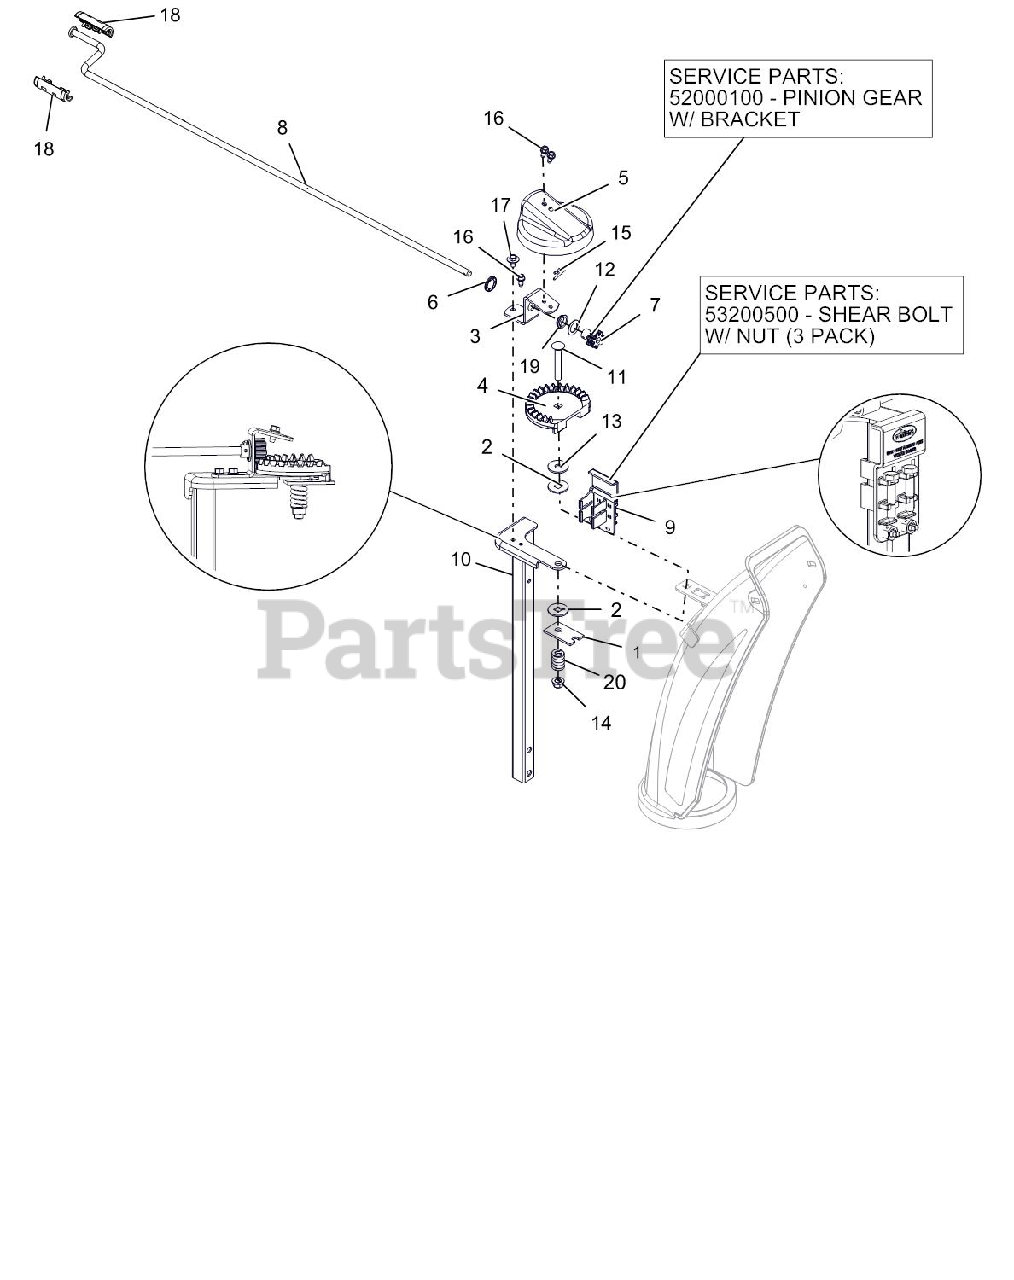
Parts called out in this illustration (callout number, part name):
1	PLATE, FRICTION
2	FRICTION WASHER
3	BRACKET, PINION GEAR
4	CHUTE GEAR
5	GEAR COVER
6	PUSHNUT .625
7	PINION GEAR W/BRACKET
7	PINION GEAR - CHUTE
8	ROD, CHUTE CRANK, COMP&SNOTEK
9	SHEAR BOLT WITH NUT
9	HOLDER W SMALL SHEAR BOLT /NUT
10	CHUTE PEDESTAL, TALL COMPACT
11	@BLT-RDHDSQNK .38-16X2.50 G5YZ
12	WSHR-THRST .625 X 1.0 X .03
13	@WSHR-FL-STL .406X1.25X.10 ZC
14	@NUT-LK-TOP-FLG .38-16 YWZC
15	PIN, SPRING CLIP
16	SCR-TAP .25-20X.50 HWH TR YWZ
17	SCR-TAP .25-20X.50 LGHWH TR YZ
18	KNOB, CHUTE CRANK - SNAP BLK
19	BUSHING, POLYLINER-.63 SNAPIN
20	SG-COMP .187X.56X1.62
